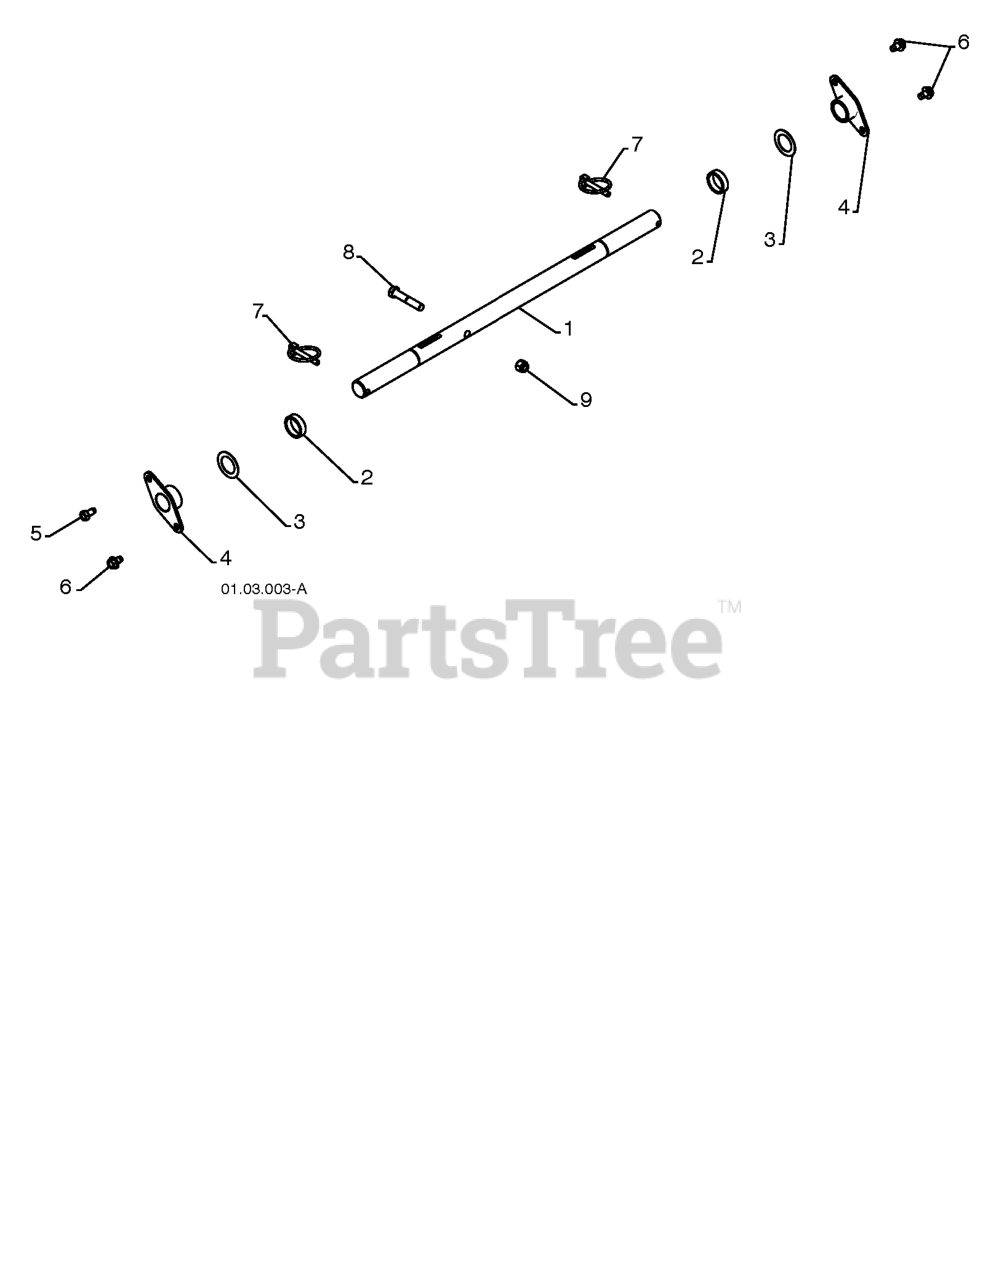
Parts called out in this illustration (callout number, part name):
1	SHAFT.AXLE.POWER.STEERING.HYD
2	SPACER.AXLE.RH
3	WASHER TRUST 1"
4	BEARING, AXLE
6	Screw 5/16-18 x 1/2 Hex, Self Tapping 5/16-18 x 1/2
7	PIN KLIK, 1/4
8	CAP.SCREW.HEX.HD.3/8-16
9	NUT
